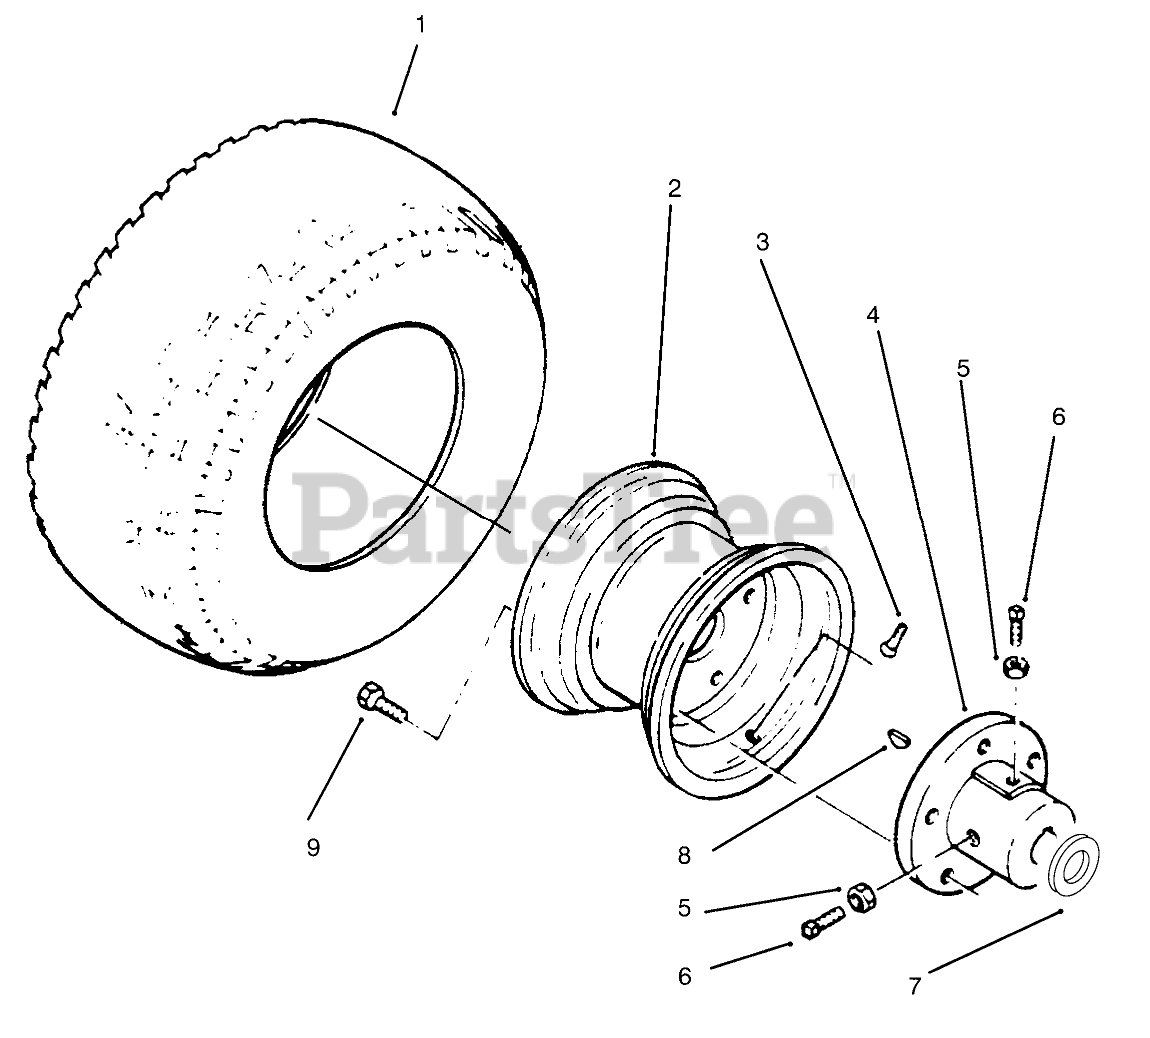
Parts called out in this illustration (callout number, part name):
1	TIRE
2	WHEEL
3	VALVE
4	Hub Rear
5	NUT-JAM
6	SCREW-SET, SQH
7	WASHER-THRUST
8	KEY-WOODRUFF
9	BOLT-LUG
